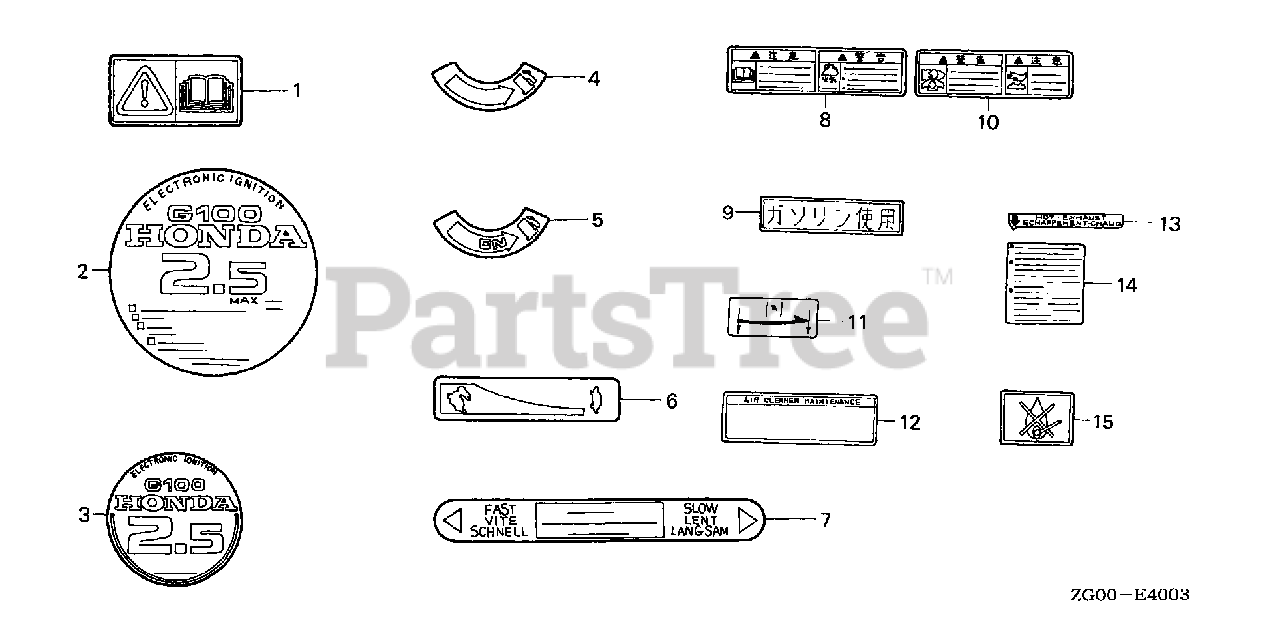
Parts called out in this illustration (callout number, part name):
1	MARK, OPERATOR CAUTION
2	EMBLEM (EXP)
3	EMBLEM
4	MARK, PETCOCK (EXTERNAL)
5	MARK (EXTERNAL)
6	MARK, THROTTLE INDICATION (ENGLISH)
7	MARK, THROTTLE (ENGLISH/FRENCH)(GERMAN)
